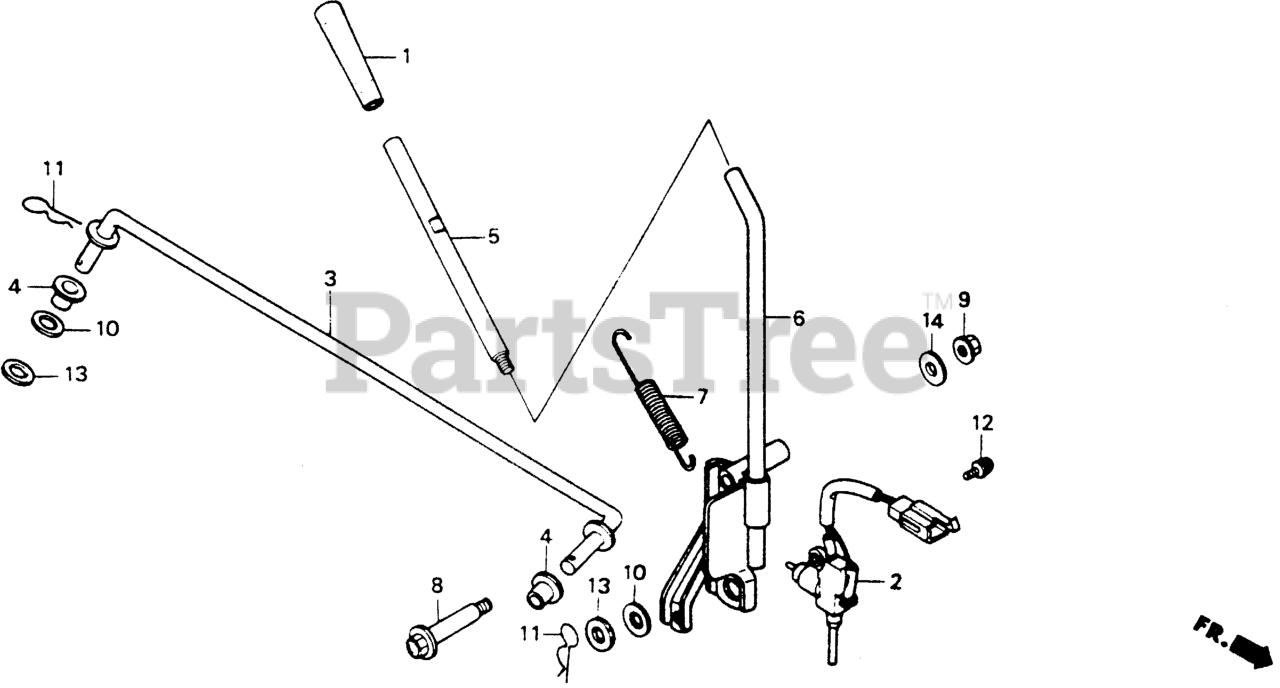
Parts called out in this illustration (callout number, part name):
1	GRIP, CHANGE LEVER
2	SWITCH ASSY., P.T.O. CLUTCH (NOT AVAILABLE)
3	ROD, P.T.O. CLUTCH
4	BUSH, P.T.O. ROD
5	JOINT, P.T.O. CLUTCH LEVER
6	LEVER, P.T.O. CLUTCH
7	SPRING, P.T.O. CLUTCH
8	BOLT, P.T.O. CLUTCH LEVER
9	NUT, FLANGE (8MM)
10	WASHER, P.T.O.
11	PIN, SNAP (7MM)
12	SCREW-WASHER (4X14)
13	WASHER, PLAIN (10MM)
14	WASHER, PLAIN (8MM)
